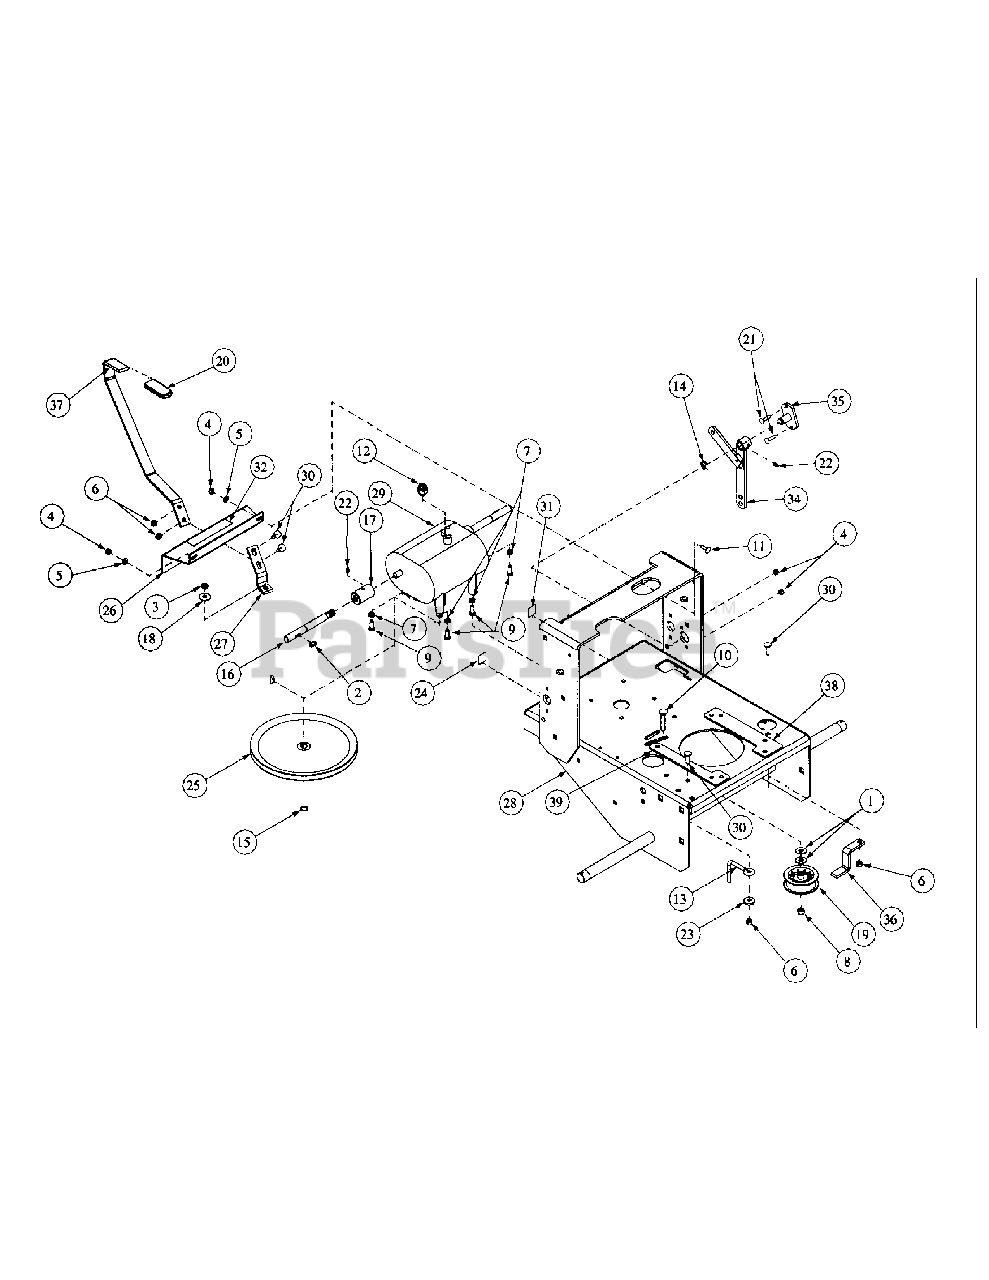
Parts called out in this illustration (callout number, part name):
1	Flat Washer, 3/8 Zinc
2	Woodruff Key, 3/16 x 3/4
3	Jam Nut, Insert Lock, 3/8-24
4	Lock Nut, Nylon Insert, 1/4-20
5	Flat Washer, 1/4 Zinc
6	Nut, 5/16-18 Nylock
7	Lock Washer, 5/16 Zinc
8	Lock Nut, Nylon Insert, 3/8-16
9	Hex Cap Screw, 5/16-18 x 3/4
10	Carriage Bolt, 3/8-16 x2
11	Carriage Bolt, 1/4-20 x .750
12	Switch, WB Transmission
13	Drive Belt Guide
14	E-Ring, 5/8
15	External Retainer Ring
16	Jackshaft w/ Heavy Spline
17	Coupling w/Heavy Spline
18	Bell Washer, .39 ID x 1.13 OD x .062
19	Flat Idler Pulley w/Adapter
20	Grip, .250 x 1 x 3-1/2, Yellow
21	Carriage Bolt, 1/4-20 x 1.00
22	Grease Fitting, 1/4-28 x 3/16
23	Idler Washer
24	Decal "Made In America"
25	Transmission Pulley
26	Shift Plate
27	Shift Arm
28	Engine Deck Assembly
29	Transmission, 5 Speed
30	Carriage Bolt, 5/16-18 x 1
31	Label, Warning, Open Belt Drive
32	Label, Mower Instruction
34	Clutch, Bellecrank Weldment
35	Bellecrank Pivot, Weldment
36	Engine Belt Guide
37	Shift Handle
38	Engine Spacer, RH
39	Engine Spacer, LH
